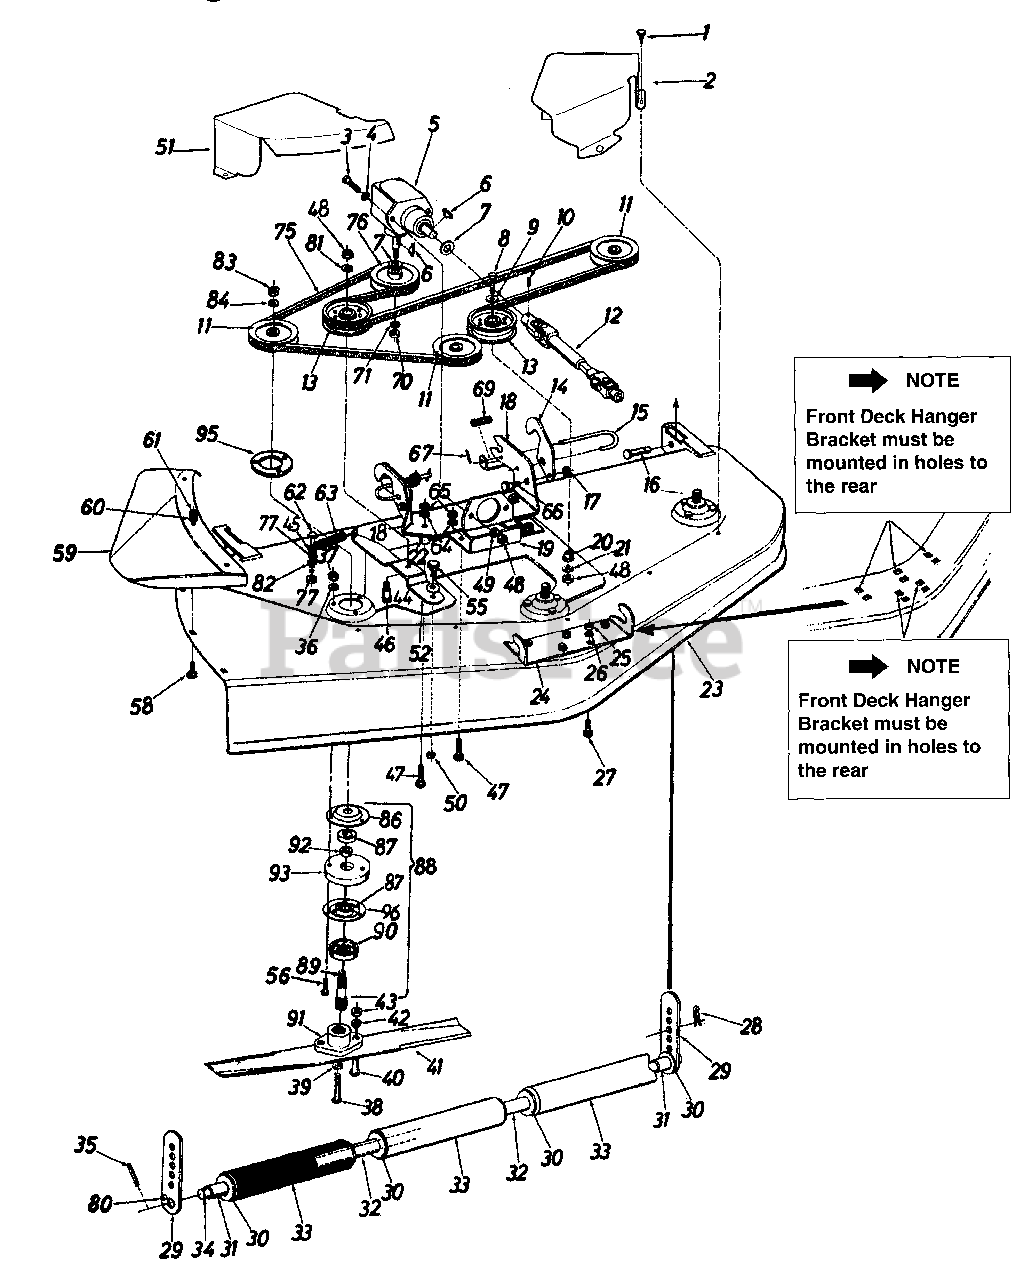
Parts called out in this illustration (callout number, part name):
1	Hex TT-Tap Scr. 1/4-20 x .5" Lg.
3	Hex Bolt 3/8-16 x 1.25" Lg.
4	Ext. L-Wash. 3/8" I.D.
5	Right Angle Drive
6	#9 Hi-Pro Key 3/16 x 3/4" Dia.
7	Fl-Wash. 29/32" I.D.
8	Hex Bolt 3/8-16 x 2.25" Lg.
9	Fl-Wash. 3/8" I.D.
10	Sq. Hd. Set Scr. 3/8-16 x .50"
11	Deck Pulley
12	Universal Drive Shaft Assembly
12	Universal Drive Half: Male
12	Universal Drive Half: Female
13	Deck Idler Pulley
14	Hanger Lock
15	Release Pin
16	Clevis Pin .50" Dia.
17	Hex L-Nut 5/16-18 Thd.
21	L-Wash. 3/8" I.D.
26	L-Wash. 5/16" I.D.
27	Carriage Bolt 5/16-18 x .75" Lg.
28	Internal Cotter Pin
30	Fl-Wash. .75" I.D. x 1.5" O.D.
31	Spacer .758" I.D. x 1.25" O.D. x .530
34	Roller Shaft
35	Roll Pin 3/16 x 1.25"
36	L-Wash. 5/16" I.D.
37	Hex L-Nut 5/16-24 Thd.
38	Hex Self-Tap Scr. 3/8-24 x .75" Lg. (Gr. 5)
38	Hex Bolt 3/8-24 x .88" Lg. (Gr. 5)
39	L-Wash. 3/8" I.D.H.D.
40	Hex Bolt 5/16-24 x 1" Lg.
41	Blade 17"
42	L-Wash. 5/16" I.D.
43	Hex L-Nut 5/16-24 Thd.
44	Spr. Wash. .445" I.D.
45	Fl-Wash. 1/4" I.D.
46	Shld. Bolt .625" Dia. x .96"
47	Carriage Bolt 5/16-18 x 1.5" Lg.
48	Hex Nut 3/8-16 Thd.
49	L-Wash. 3/8" I.D.
50	Hex L-Nut 7/16-14 Thd.
56	Hex Bolt 5/16-24 x 1.5" Lg. (Grade 5)
56	Screw-Rib Neck 5/16-24 x 1.12" Lg.
58	Carriage Bolt 5/16-18 x .75" Lg.
60	L-Wash. 5/16" I.D.
61	Hex Nut 5/16-18 Thd.
62	Hex Bolt 1/4-28 x 1-3/4" Lg.
63	Extension Spring
64	L-Wash. 5/16" I.D.
65	Hex Nut 5/16-18 Thd.
66	Shld. Bolt
67	Roll Pin 1/8" Dia.
69	Compression Spring
70	Hex L-Nut 5/8-18 Thd.
71	L-Wash. 5/8" I.D.
75	V-Belt 1/2"
76	Drive Pulley
77	Hex L-Nut 1/4-28 Thd.
80	Spring Pin Spiral 1/4" Dia. 1.00" Lg.
81	Bell-Wash. 3/8" I.D. x .87" O.D.
82	L-Wash. 1/4" I.D.
83	Hex Jam Nut 5/8-18 Thd.
84	L-Wash. 5/8" I.D.
86	Bearing Housing
87	Ball Bearing
88	Deck Spindle Assembly 3/4"
88	Deck Spindle Assembly 1"
89	Spindle 3/4"
90	Bearing Shield
91	Blade Adapter 3/4"
91	Blade Adapter 1"
92	Spacer
95	Spindle Reinforcement Plate
96	Open Bearing Housing
96	Bearing Housing w/bearing 741-0919A
